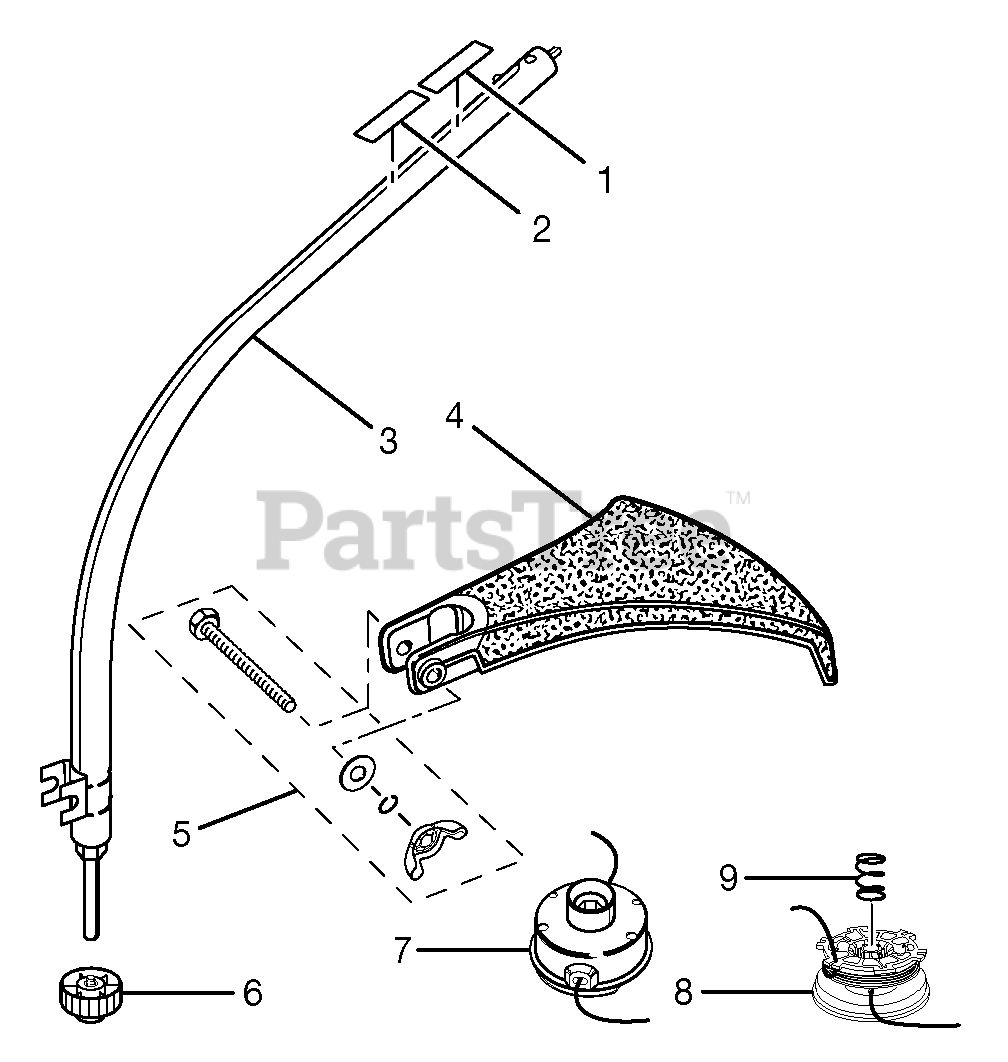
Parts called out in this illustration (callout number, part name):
1	Expand-it Label
2	Warning Decal
3	Curved Shaft Assembly
4	Grass Deflector
5	Fastener Kit
6	Spool Retainer (Black)
7	Complete String Head (.080 in.)
8	Spool and String (.080 in.)
9	Compression Spring
